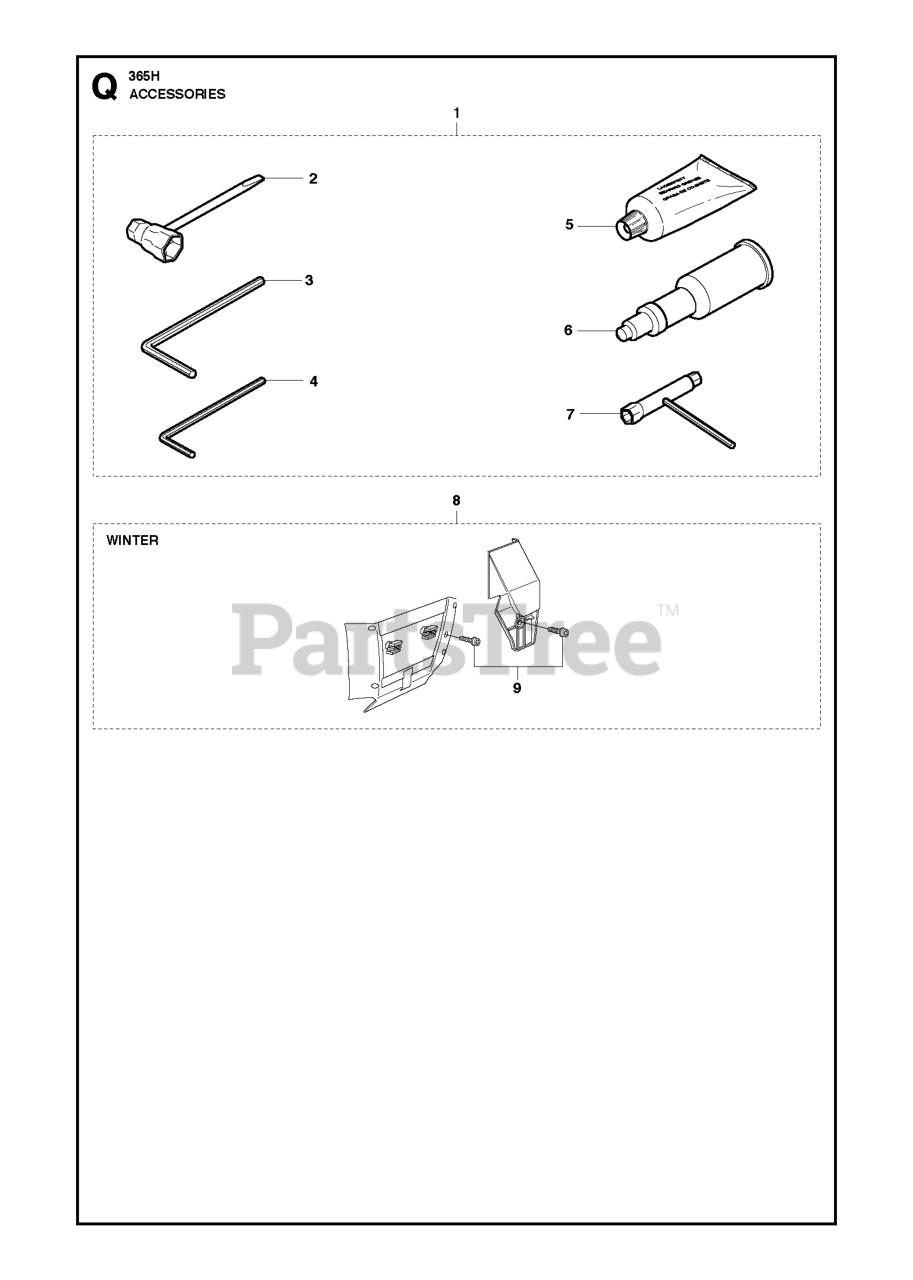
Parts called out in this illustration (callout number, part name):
2	COMBI TOOL
3	L-SPANNER
4	L-SPANNER
5	GREASE
6	Grease Gun
7	COMB.TOOL 8-10-14
8	WINTER KIT
